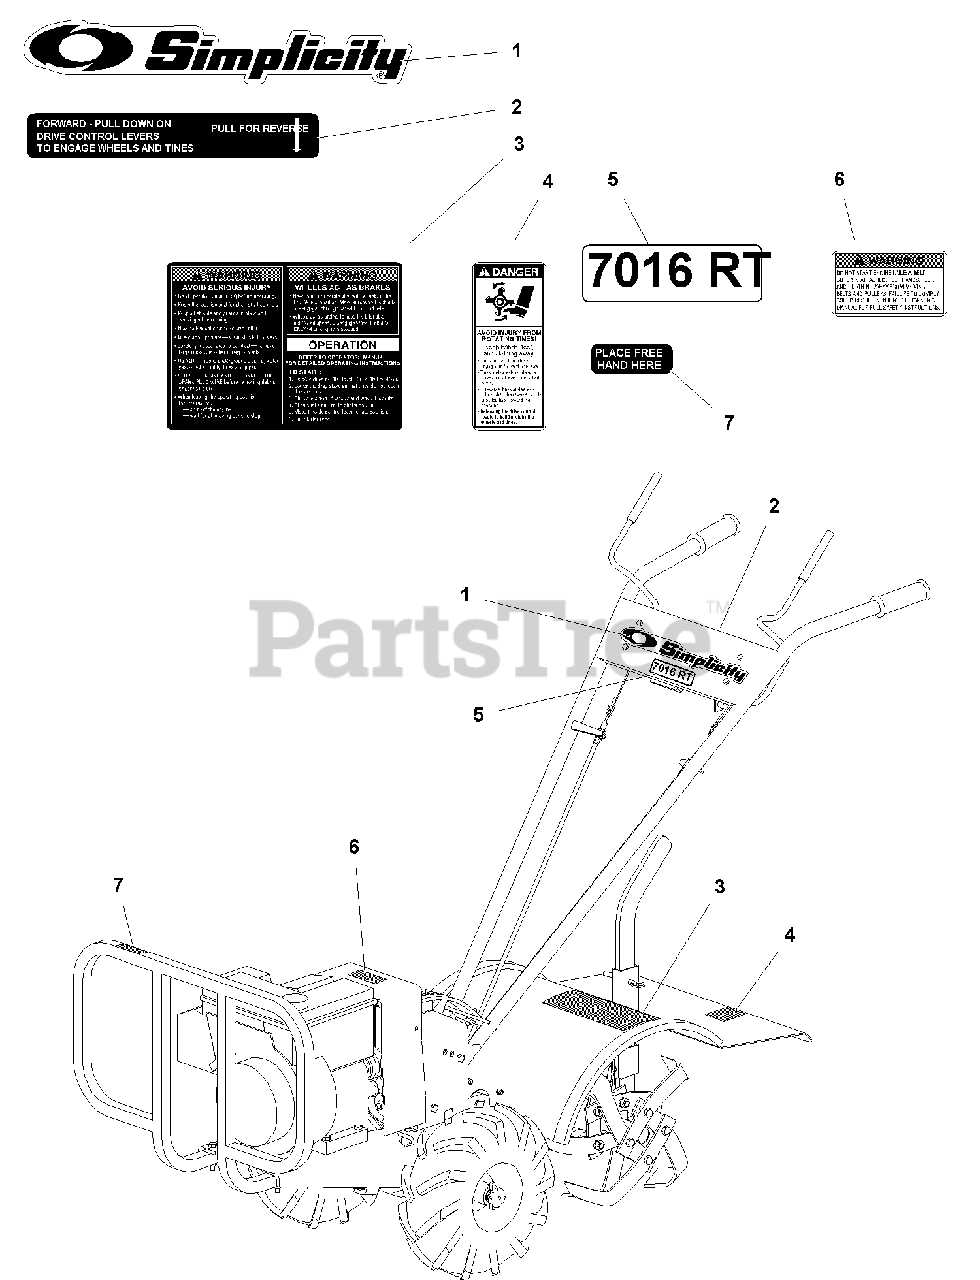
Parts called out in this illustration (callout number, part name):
1	DECAL, SIMPLICITY, w/Logo
2	DECAL, Console Forward/Reverse Instructions
3	DECAL, Hood, Operator Instructions Label
4	DECAL, Danger, Tine Hood Label
5	DECAL, 7016 RT
6	DECAL, Warning, Belt Cover
7	DECAL, Brush Bar
